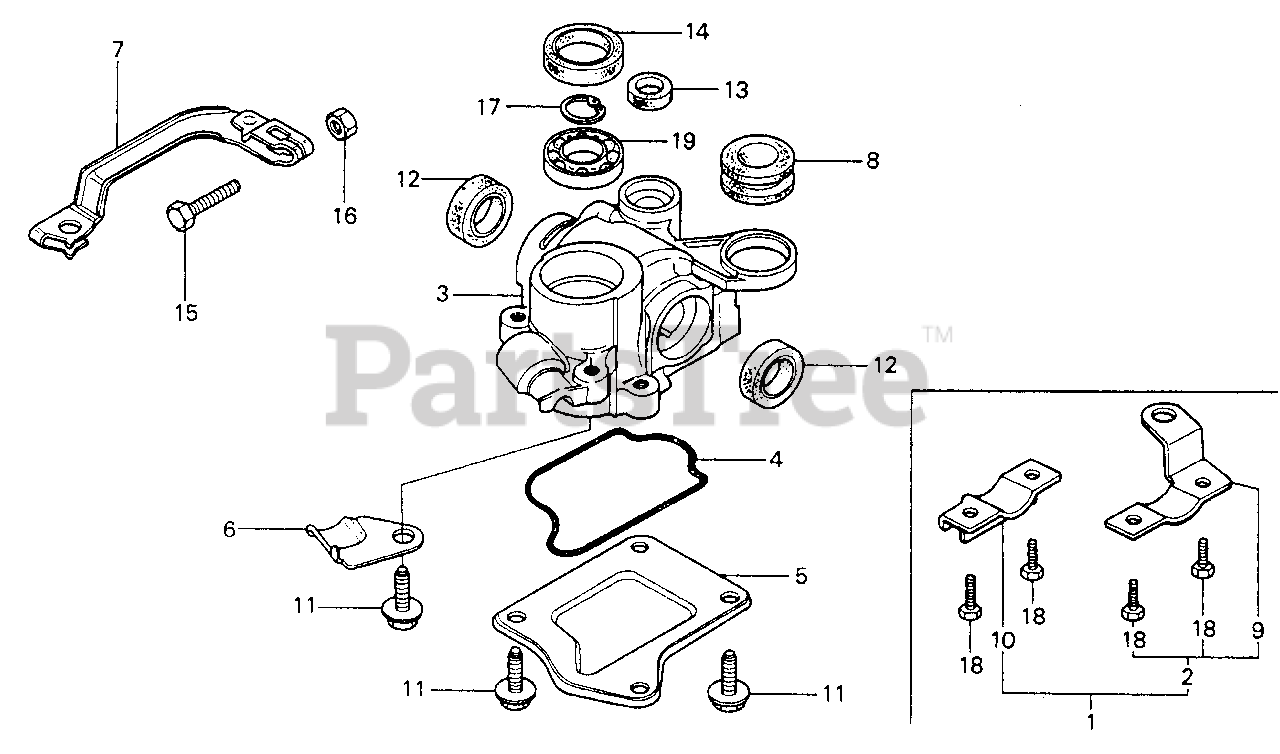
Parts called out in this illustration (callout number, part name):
1	BRACKET KIT, STOPPER
2	STOPPER KIT, CASE
3	CASE, GEAR (UPPER)
4	O-RING, CASE
5	COVER, GEAR CASE
6	HOLDER, WIRE
7	ARM, CLUTCH
8	MOUNT, RUBBER (NOT AVAILABLE)
9	STOPPER, CASE
10	BRACKET, L. PANEL (NOT AVAILABLE)
11	BOLT, FLANGE (6X12) (CT200)
12	OIL SEAL (12X22X5)
13	OIL SEAL (8X14X5)
14	OIL SEAL (18X28X6)
14	OIL SEAL (18X38X6) (NOT AVAILABLE)
15	BOLT, HEX. (6X20)
16	NUT, HEX. (6MM)
17	CIRCLIP (INNER) (28MM)
18	BOLT, FLANGE (6X16)
19	BEARING, RADIAL BALL (6001)
